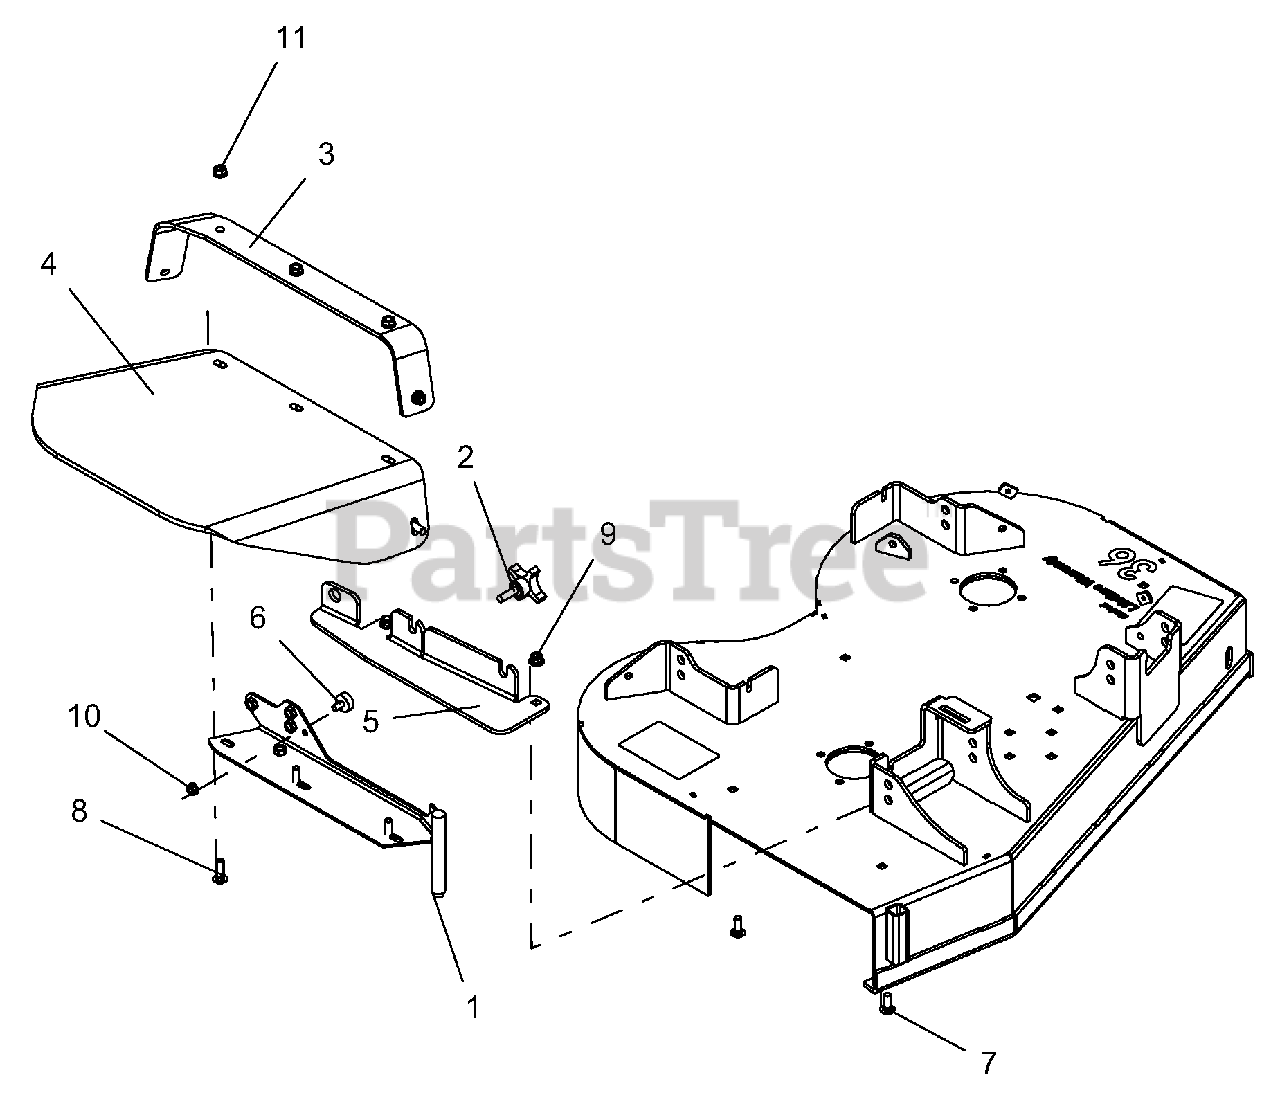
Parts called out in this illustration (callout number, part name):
1	WLDT. DISCHARGE-RED
2	KNOB, 3/8 X 1.25 - 4 PRONG
3	STRAP, RUBBER DISCHARGE CHUTE
4	SHIELD, RUBBER DISCHARGE
5	BRKT, DISCHARGE 36 STANCE
6	BUMPER, RUBBER
7	BLT-RDHDSQNK .38-16X1.00 G5 YWZC
8	BLT-RDHDSQNK .38-16X1.25 G5 YWZC
9	NUT-LK-NYL-FLG .38-16 YWZC
10	@NUT-SPNLK-FLG .312-18 YWZC
11	@NUT-SPNLK-FLG .375-16 YWZC
